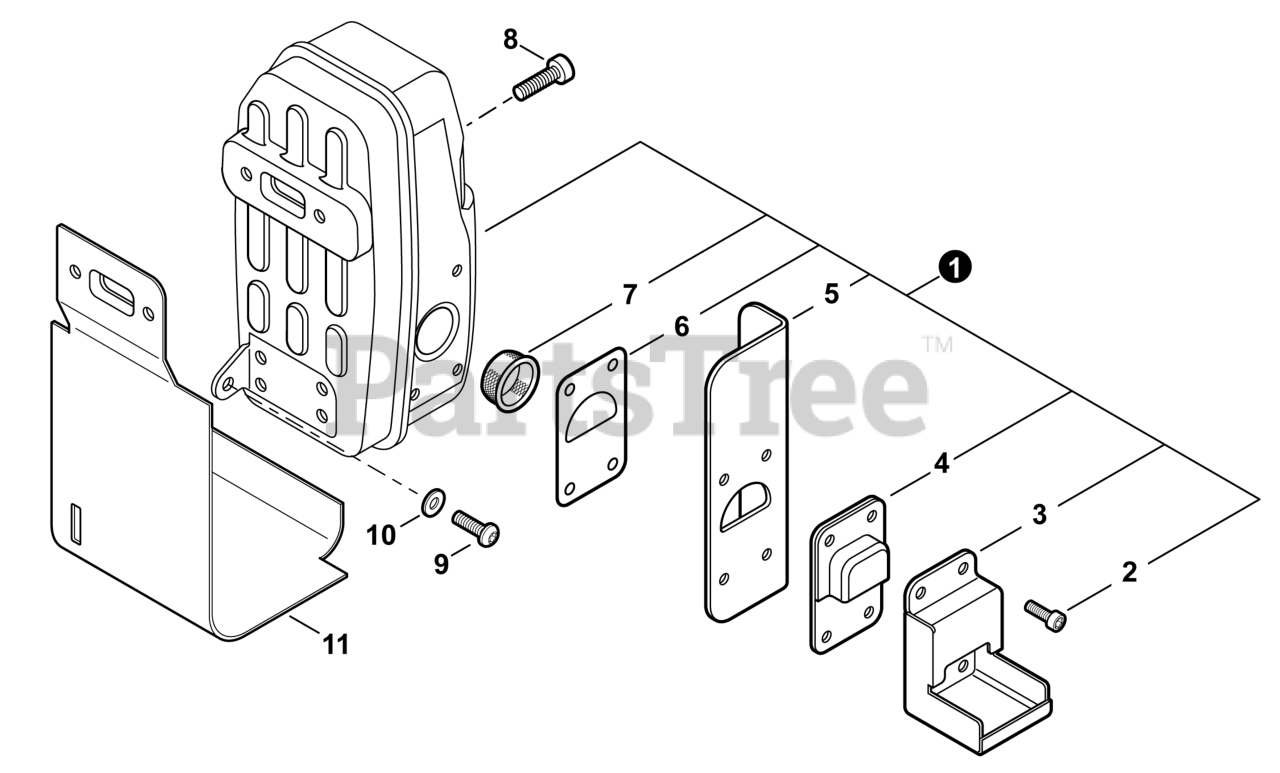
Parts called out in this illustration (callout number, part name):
1	MUFFLER ASSY
2	BOLT, TORX 4x12
3	GUIDE, EXHAUST
4	GUIDE, EXHAUST
5	HEAT SHIELD, EXHAUST
6	GASKET, EXHAUST
7	SCREEN, SPARK ARRESTER
8	BOLT, TORX 6x20
9	BOLT, TORX 5x16
10	WASHER 5.5x16x2T
11	HEAT SHIELD, EXHAUST
